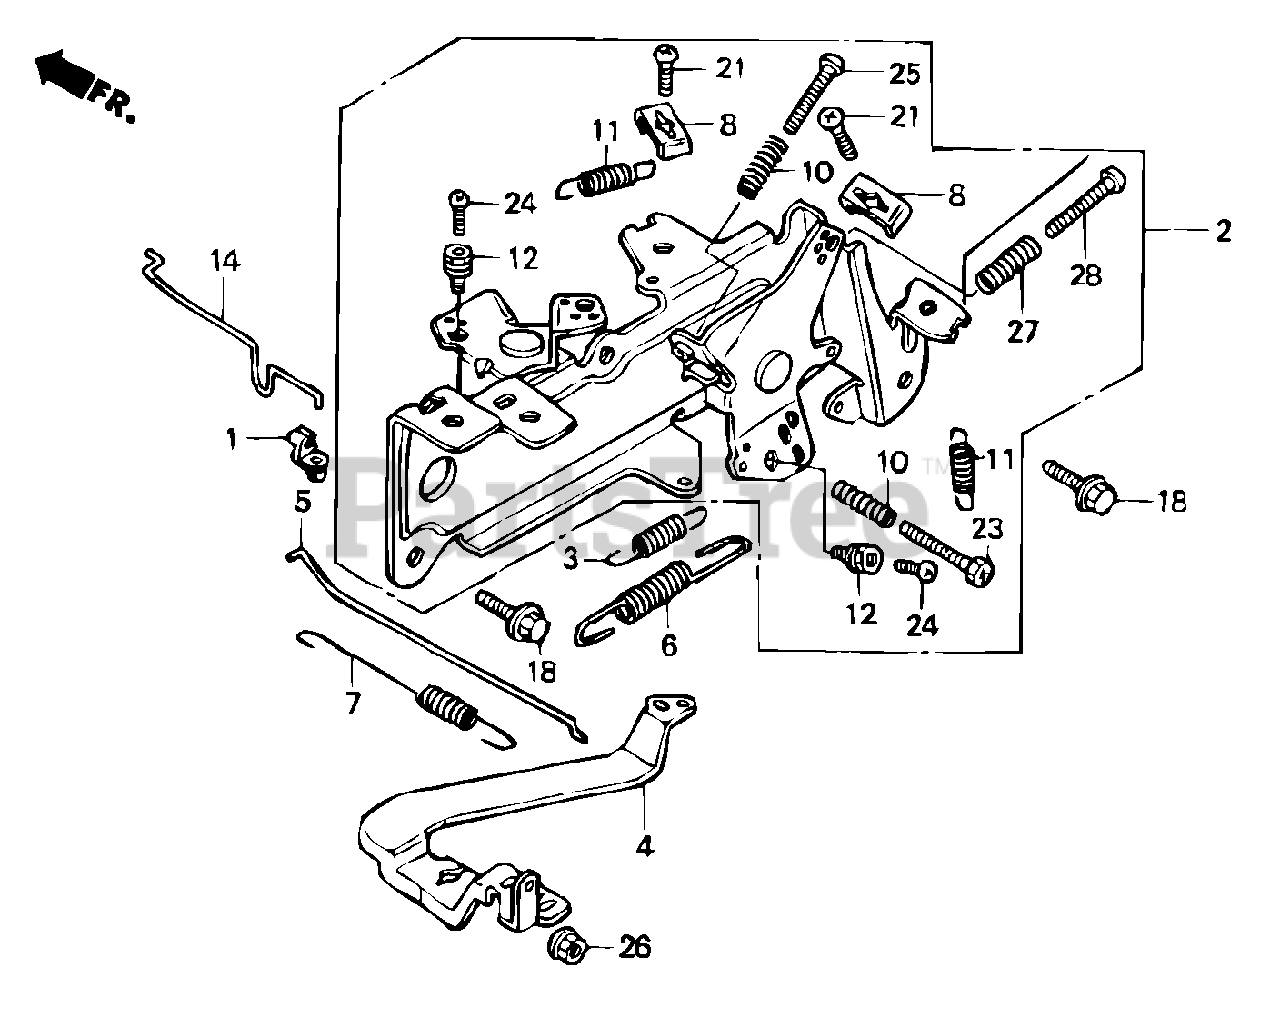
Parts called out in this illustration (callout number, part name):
1	Joint, Rod
2	Control Assembly
3	Spring, Starter
4	Arm, Governor
5	Rod, Governor
6	Spring, Governor
7	Spring, Throttle Return
8	Holder, Cable
10	Spring, Control Adjusting
11	Spring, Cable Return
12	Holder, Cable
14	Rod, Choke Control
18	Bolt, Flange (6x14)
21	Bolt, Slot (5x16)
23	Bolt, Slot (5x25)
24	Bolt, Recessed (4x6)
25	Screw, Pan (5x25)
26	Nut, Flange (6mm)
